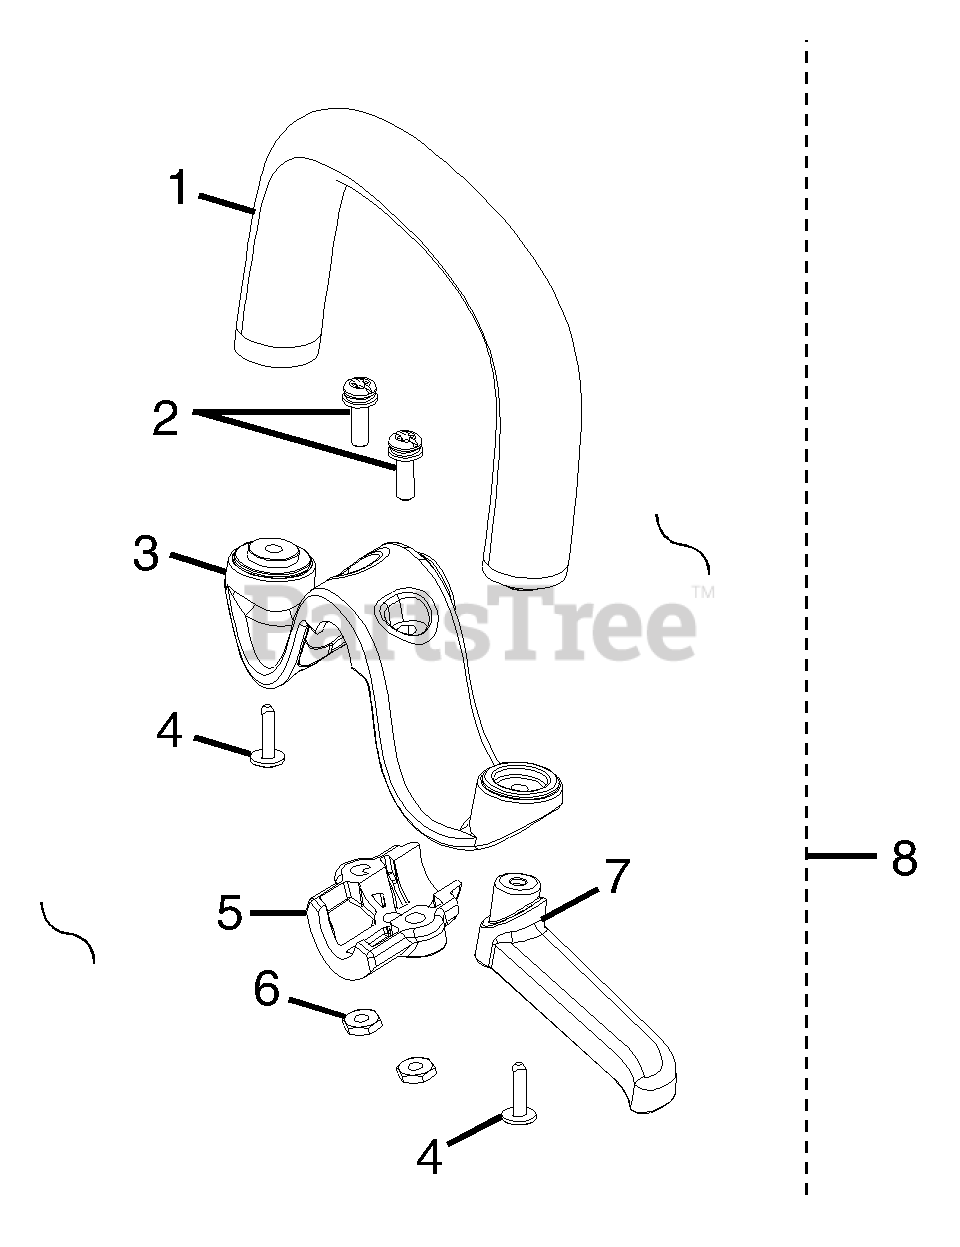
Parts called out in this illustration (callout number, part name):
1	ASSIST HANDLE W/GRIP
2	SCREW (12-24 x 1 SEMS)
3	M CLAMP
6	HEX NUT (12-24)
7	BARRIER BAR
8	ASSIST HANDLE ASSEMBLY
